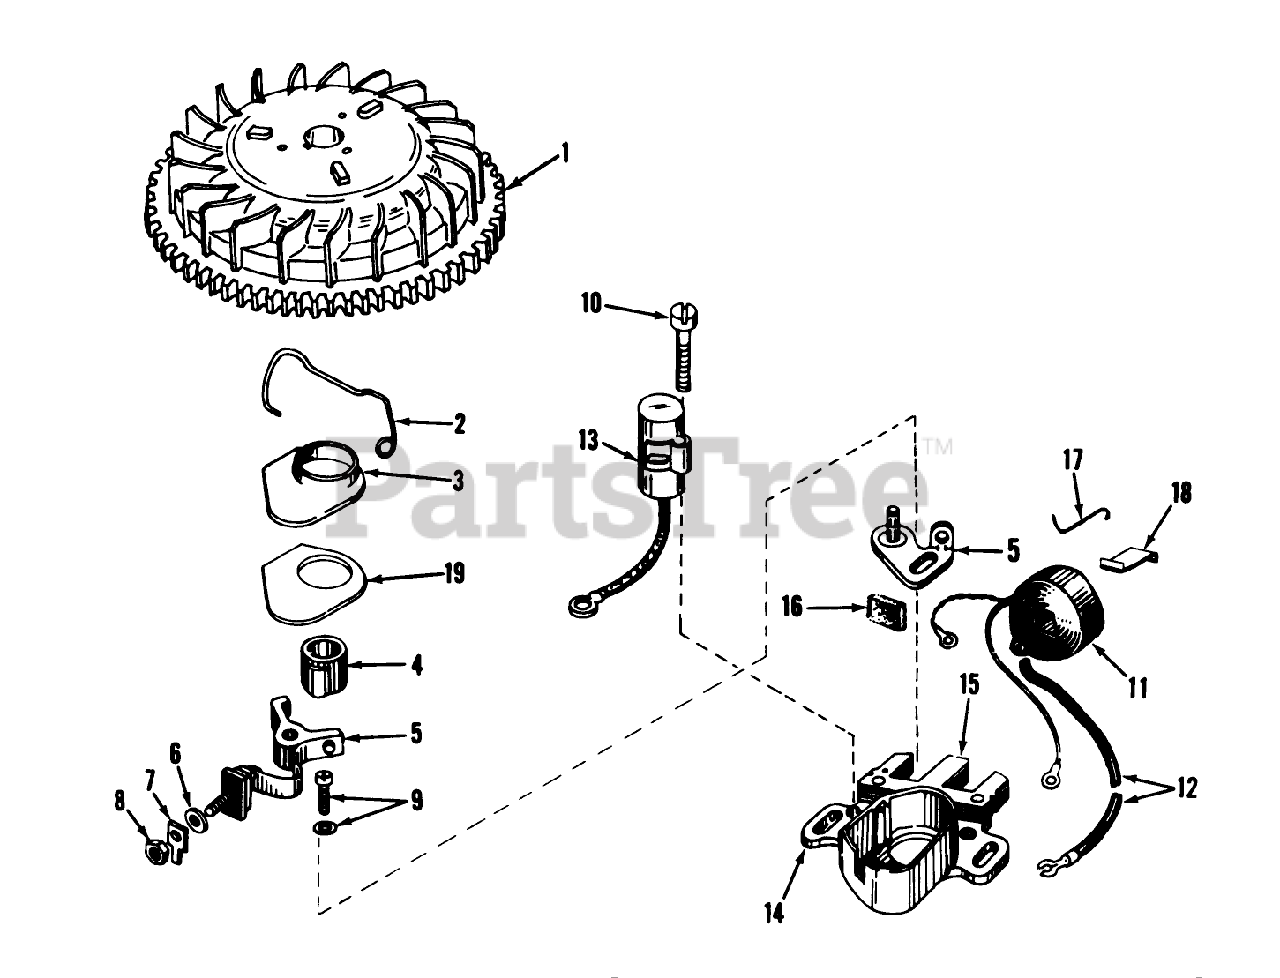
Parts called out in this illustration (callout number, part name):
1	FIywheel
2	Spring Breaker Box
3	Cover, Dust
4	Cam, Breaker
5	Breaker Assy.
6	Washer
7	Terminal, Ground
8	DECAL
9	Breaker Screw
10	Condenser Screw
11	Coil Assy. (Incl. No. 12)
12	Wire, Lead
13	Condenser
14	Core Plate
15	Stator Assy., (Incl. Nos. 2, 3, 5 thru 14 16 thru 19)
16	Felt,Cam Wiper
17	Clip, Coil
18	Spring Coil Wedge
19	Gasket Dust Cover
